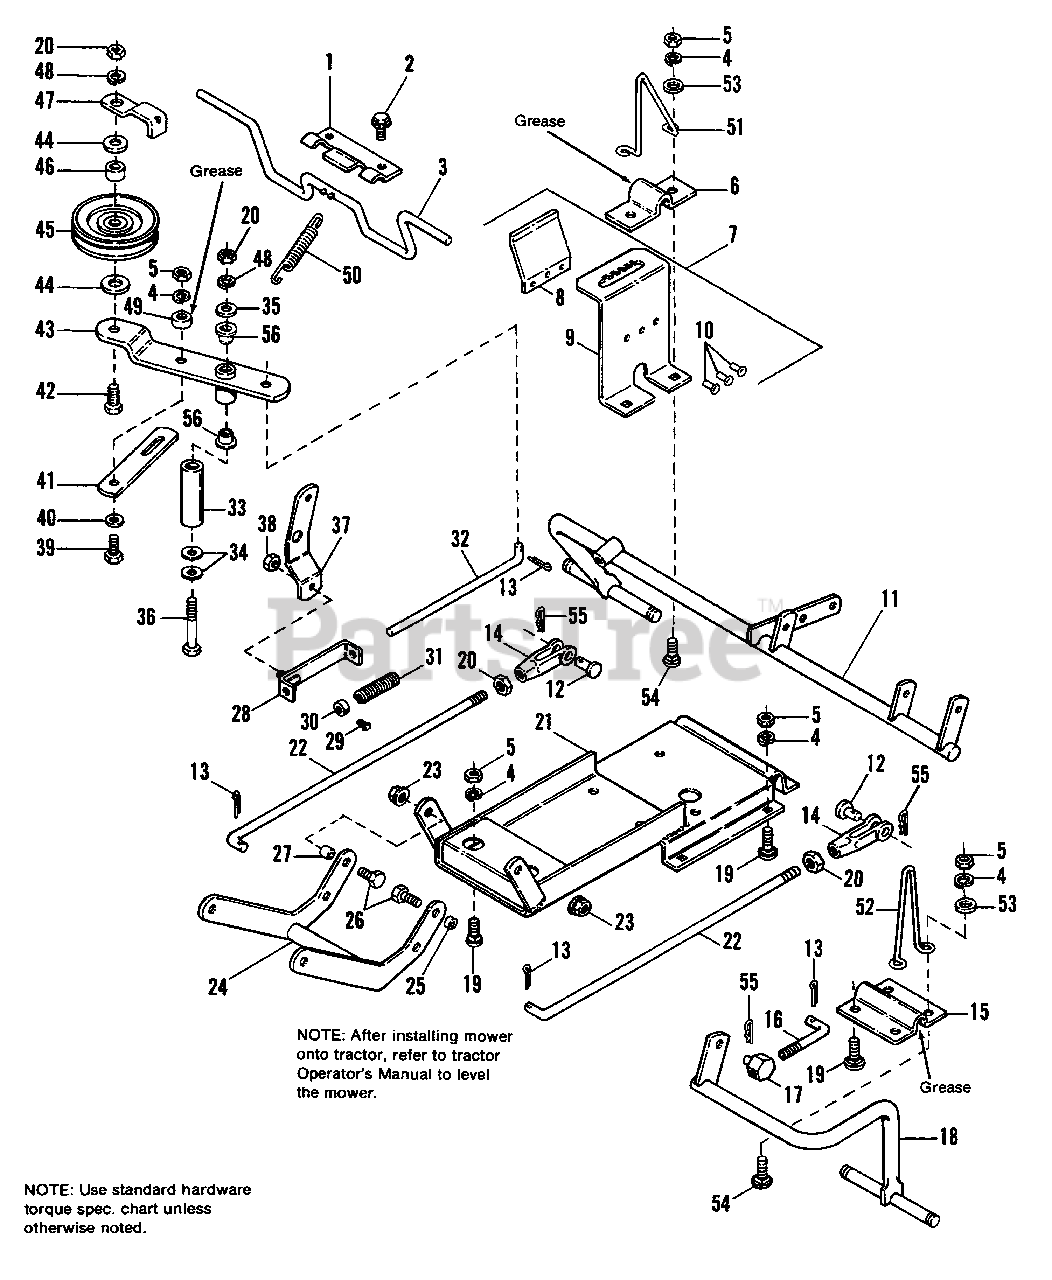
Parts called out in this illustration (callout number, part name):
1	SUPPORT, Brake
2	SCREW, Hex, Wash. Hd., Taptite, 1/4-20 x 3/8
3	ROD ASSY., Brake
4	LOCKWASHER, 5/16
5	NUT, Hex, Full, 5/16-18
7	QUADRANT ASSY. (Incl. Ref. No's. 8, 9 & 10)
8	SPRING, Flat
10	RIVET, Tubular, 3/16 x 5/16
11	SUPPORT ASSY., Roller, R.H.
12	PIN, Clevis
13	PIN, Cotter, 3/32 x 3/4
14	CLEVIS, Adjusting
15	CLAMP, Adjusting
18	SUPPORT ASSY., Roller, L.H.
19	BOLT, Carriage, 5/16-18 x 3/4
20	NUT, Hex, Full, 3/8-16
21	SUPPORT ASSY., Mower
22	ROD, Height Adjusting
23	LOCKNUT, Hex, Flange, 3/8-16
24	ARM ASSY., Rocker
26	CAPSCREW, Hex Hd., 3/8-16 x 1-1/4
28	GUIDE ASSY., Rod
29	SETSCREW, 1/4-20 x 3/8
30	COLLAR, Set
32	ROD, Clutch
35	WASHER, Plain, 3/8
36	CAPSCREW, Hex Hd., 3/8-16 x 2-3/4
37	ARM, Pivot
38	LOCKNUT, Hex, 5/16-18
39	CAPSCREW, Hex Hd., 3/8-16 x 2-3/4
40	WASHER, Plain, 1/4
41	LEVER, Brake
42	CAPSCREW, Hex hd., 3/8-16 x 1-3/4
43	LEVER ASSY., Clutch (Incl. Ref. No. 56)
44	WASHER, Plain
45	PULLEY ASSY.
47	GUARD, Spring
48	LOCKWASHER, 3/8
51	UP-STOP, R.H.
52	UP-STOP, L.H.
53	WASHER, Plain, 5/16
54	BOLT, Carriage, 5/16-18 x 1-1/4
55	CLIP, Hair Pin
